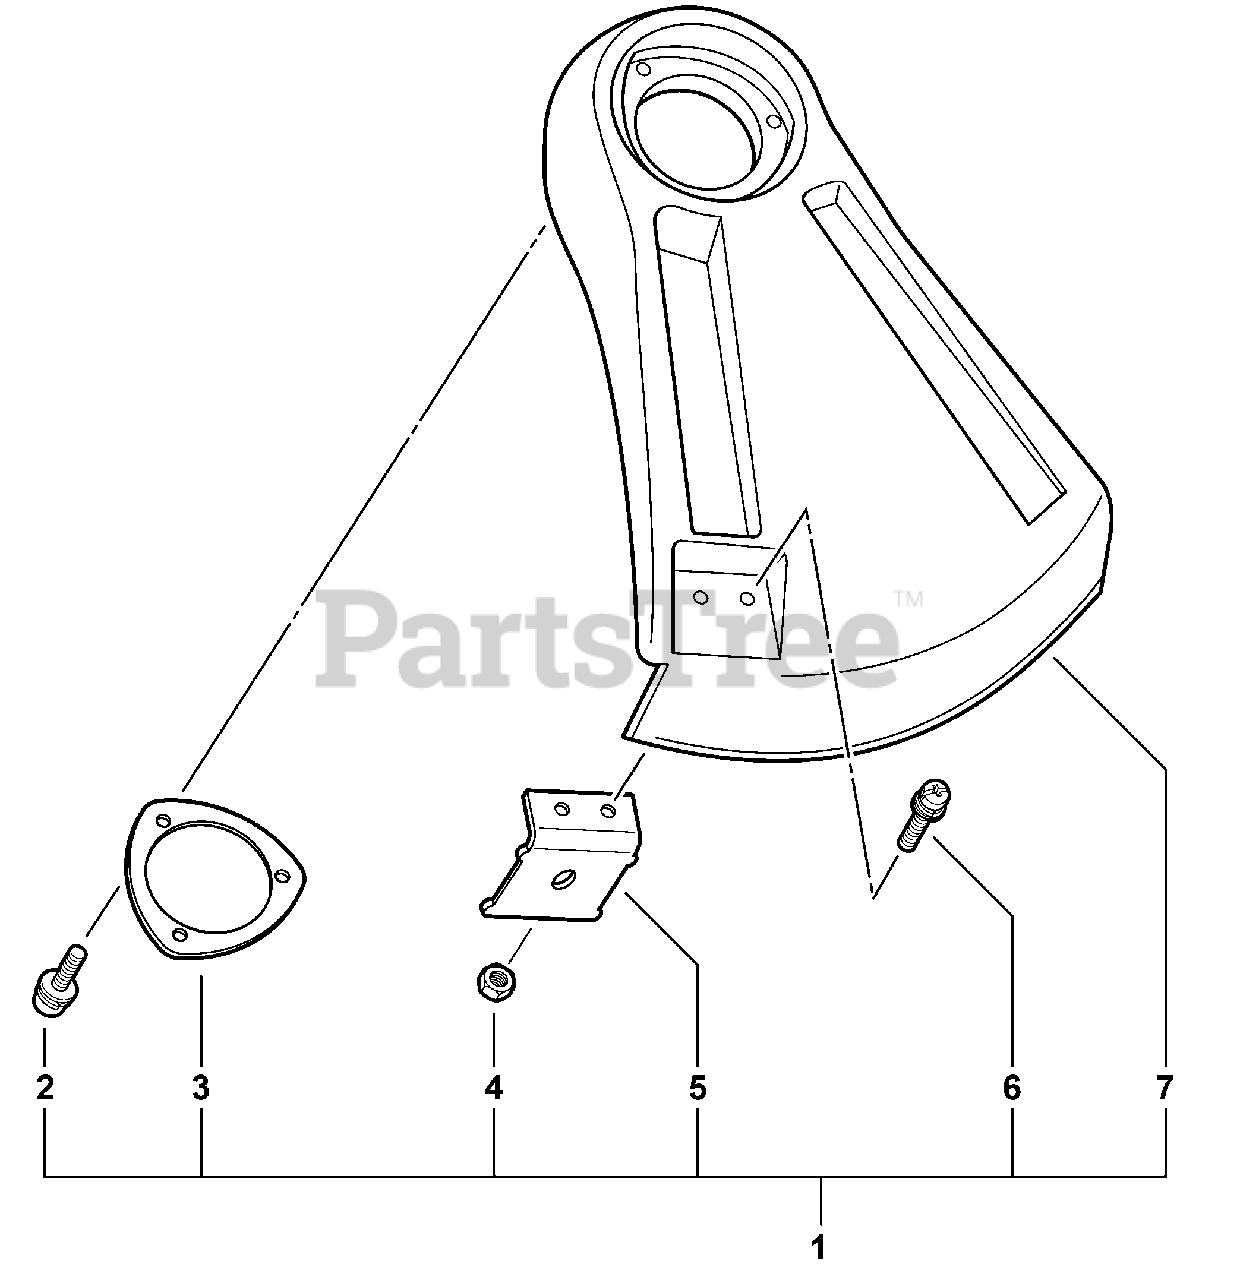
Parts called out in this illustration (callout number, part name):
1	DEBRIS SHIELD KIT - PLASTIC
2	SCREW - 5×16
3	PLATE, SHIELD
5	KNIFE,TRIMMER LINE
6	SCREW - 5×16
7	SHIELD, DEBRIS - PLASTIC
